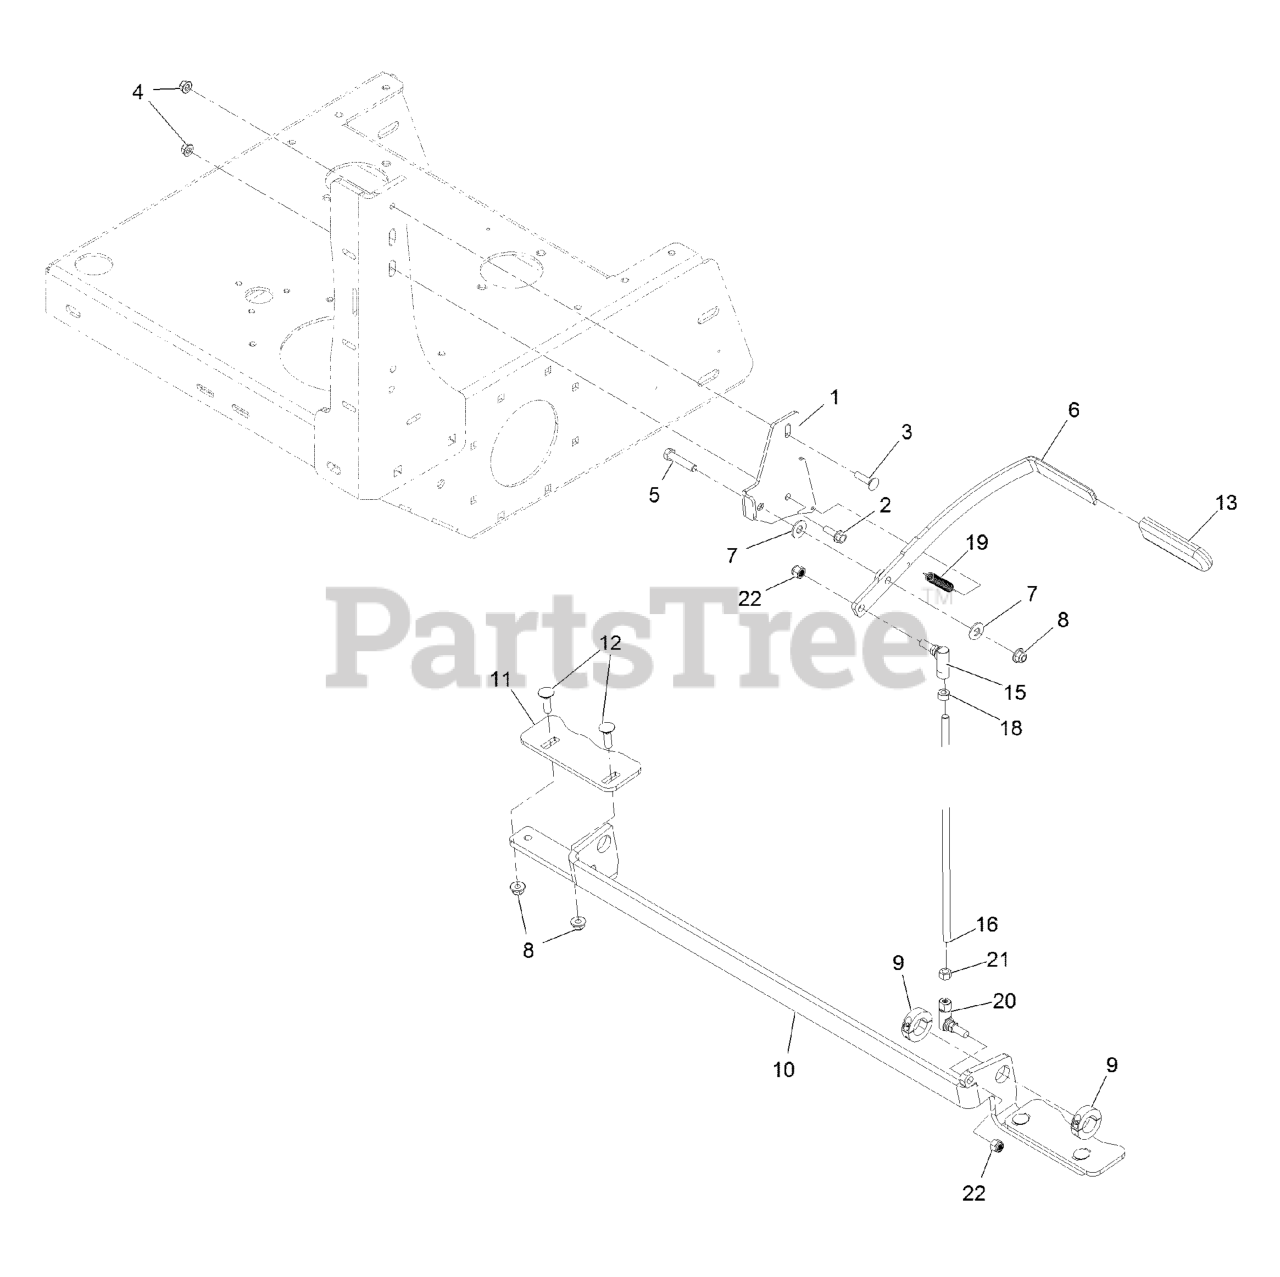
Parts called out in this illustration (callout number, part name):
1	PLATE-BRAKE
2	SCREW-HH
3	Bolt-Carriage 5/16-18 X 1 1/4
4	NUT-HF, NI
5	SCREW-HH
6	HANDLE-BRAKE
7	WASHER-PLAIN
8	NUT-HF, NI
9	COLLAR-LOCKING
10	PIVOT-BRAKE, ROD
11	PAD-BRAKE
12	Bolt-Carriage 3/8-16 X 1 1/4
13	GRIP-LEVER
15	BALL JOINT-SS
16	BRAKE ROD 14.5"
18	NUT-HEX
19	SPRING-EXTENSION
20	BALL JOINT-SS
21	NUT-HEX, LH
22	XREF 126-4803
